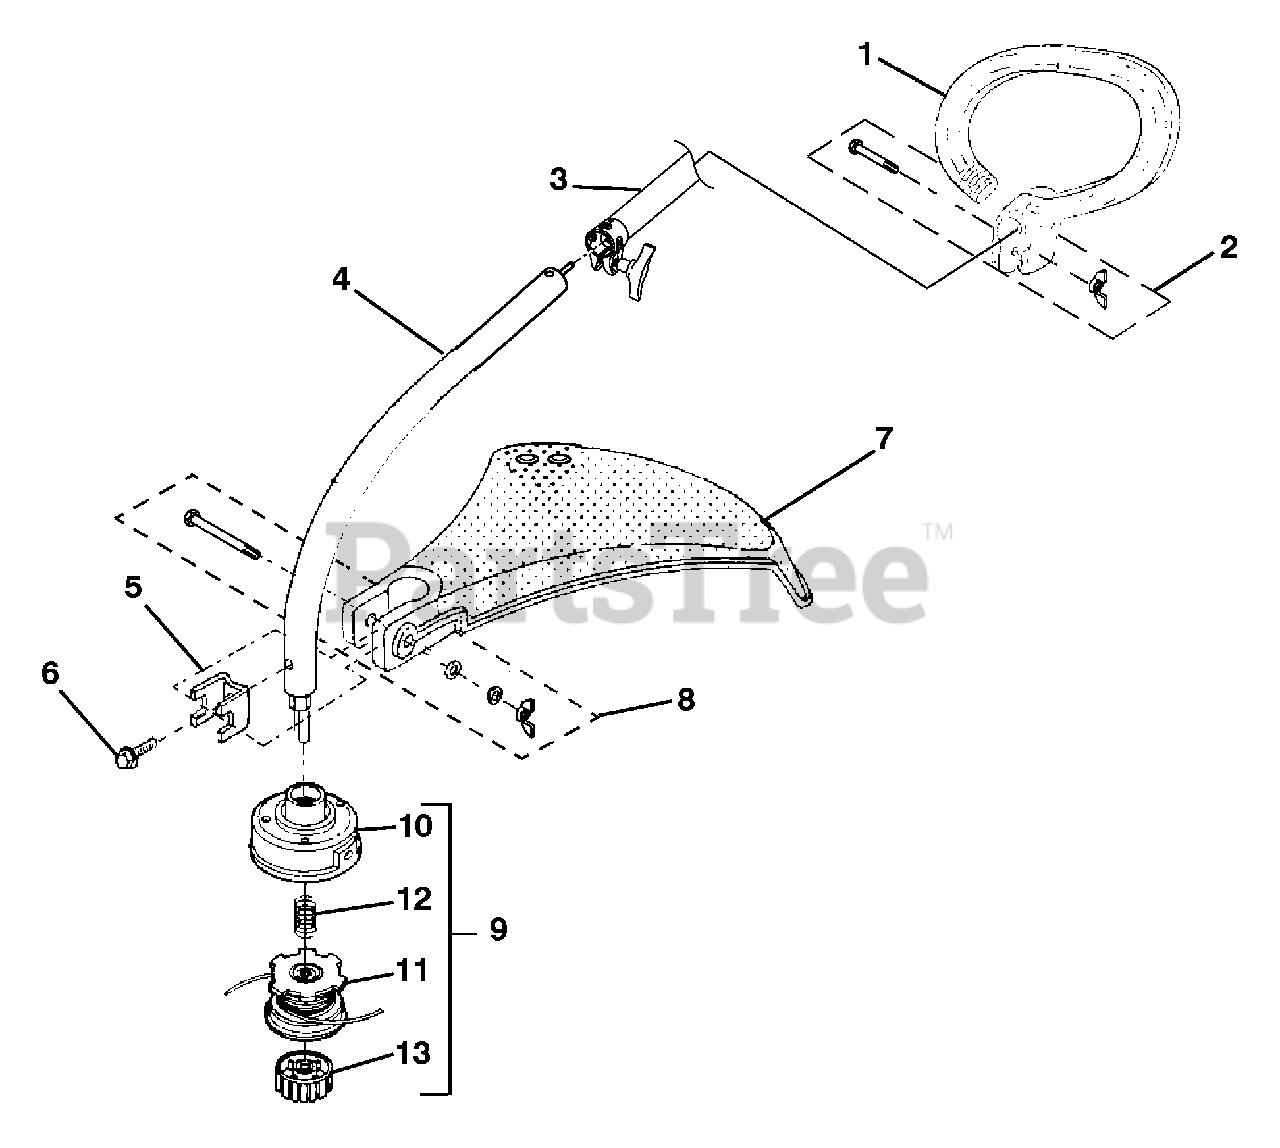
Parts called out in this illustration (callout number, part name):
1	HANDLE-Anti-Vibe
2	FASTENER KIT
3	DRIVESHAFT ASSY. (Upper)
4	DRIVESHAFT HOUSING (Lower)
5	CLAMP
6	SCREW-Sems Hex (10-24 X 3/8")
7	DEFLECTOR
8	FASTENER KIT
9	STRINGHEAD Complete (.080")
10	HOUSING & EYELET (Dual Li NE)
11	SPOOL & STRING (.080")
12	SPRING-Compression
13	RETAINER Spool (RH Thread, Black)
